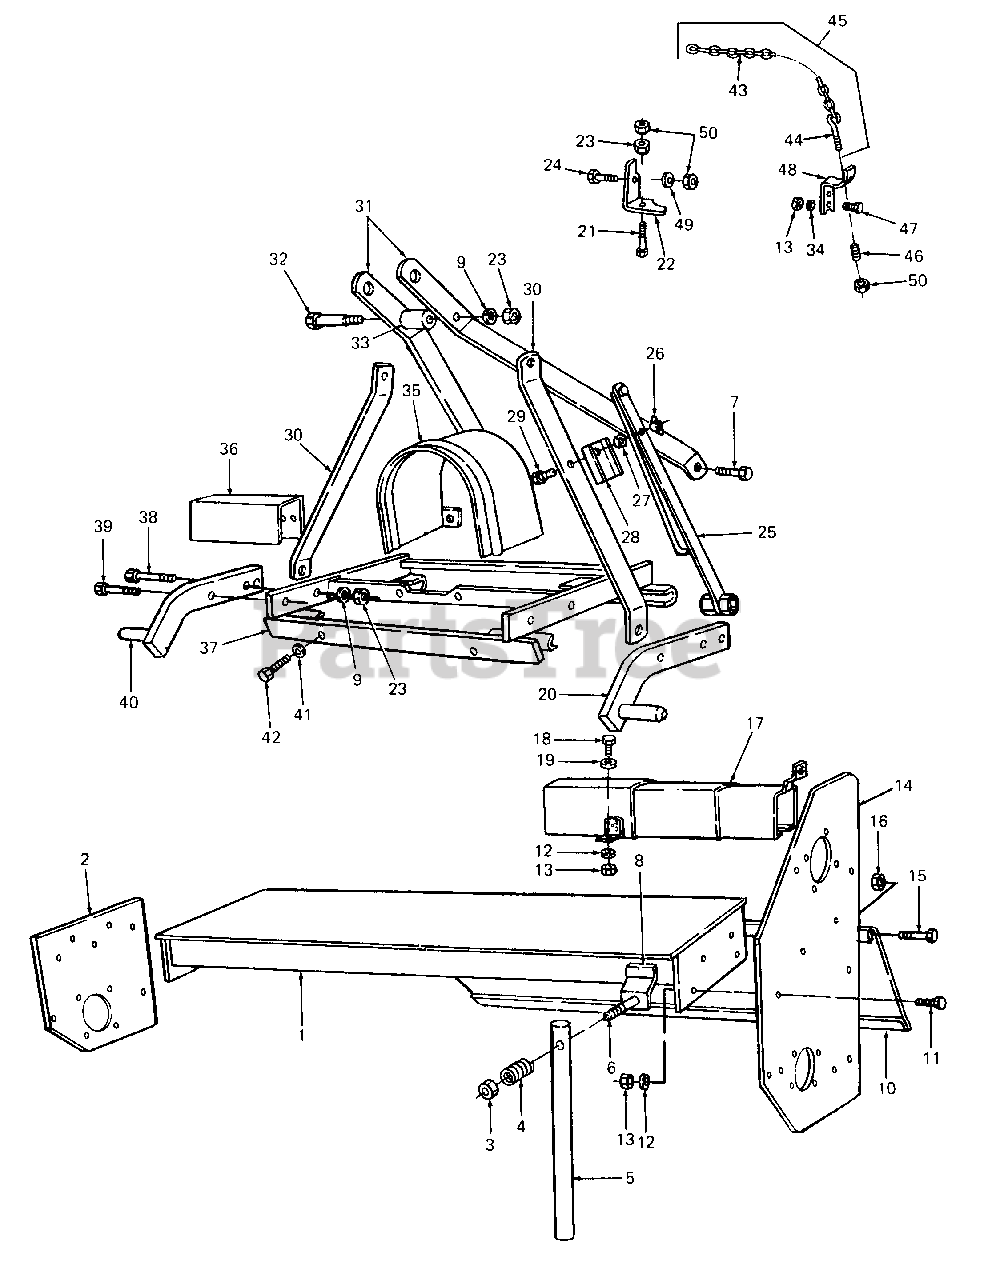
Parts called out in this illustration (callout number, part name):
1	Frame, Main
2	Panel, Right Side
4	Spring, Stand
6	Bolt, M14 X 70
7	Bolt, M12 X 35
8	Bracket, Stand Mounting
9	Washer, M12
10	Deflector, Rear
11	Bolt, M10 X 25
12	Washer, Lock, M10
14	Panel, Left Side
15	Bolt, M14 X 70
17	Cover, Expandable Protective
18	Bolt, M10 X 20
19	Washer, Flat
20	Hitch Arm, Lower Left
21	Bolt, M10 X 55
22	Bracket, Pivot
23	Nut, M12
24	Bolt, M10 X 30
25	Tool, Ratchet
26	Nut, Wing, M8
28	Cover, Locking
29	Bolt, M8 X 50
30	Support, Top Hitch
31	Arm, Top Hitch
32	Bolt, M12 X 100
34	Washer, M10
35	Cover, Protective
36	Cover w/Holes, Protective
37	Frame, Side Shift
38	Bolt, M12 X 45
39	Bolt, M12 X 55
40	Hitch Arm, Lower Right
42	Bolt, M12 X 60
44	Hook, Lifting
45	Chain Assy, Lifting
47	Bolt, M10 X 25
48	Hitch, Lifting Chain
49	Washer, Flat
50	Nut, Self Locking, M10
